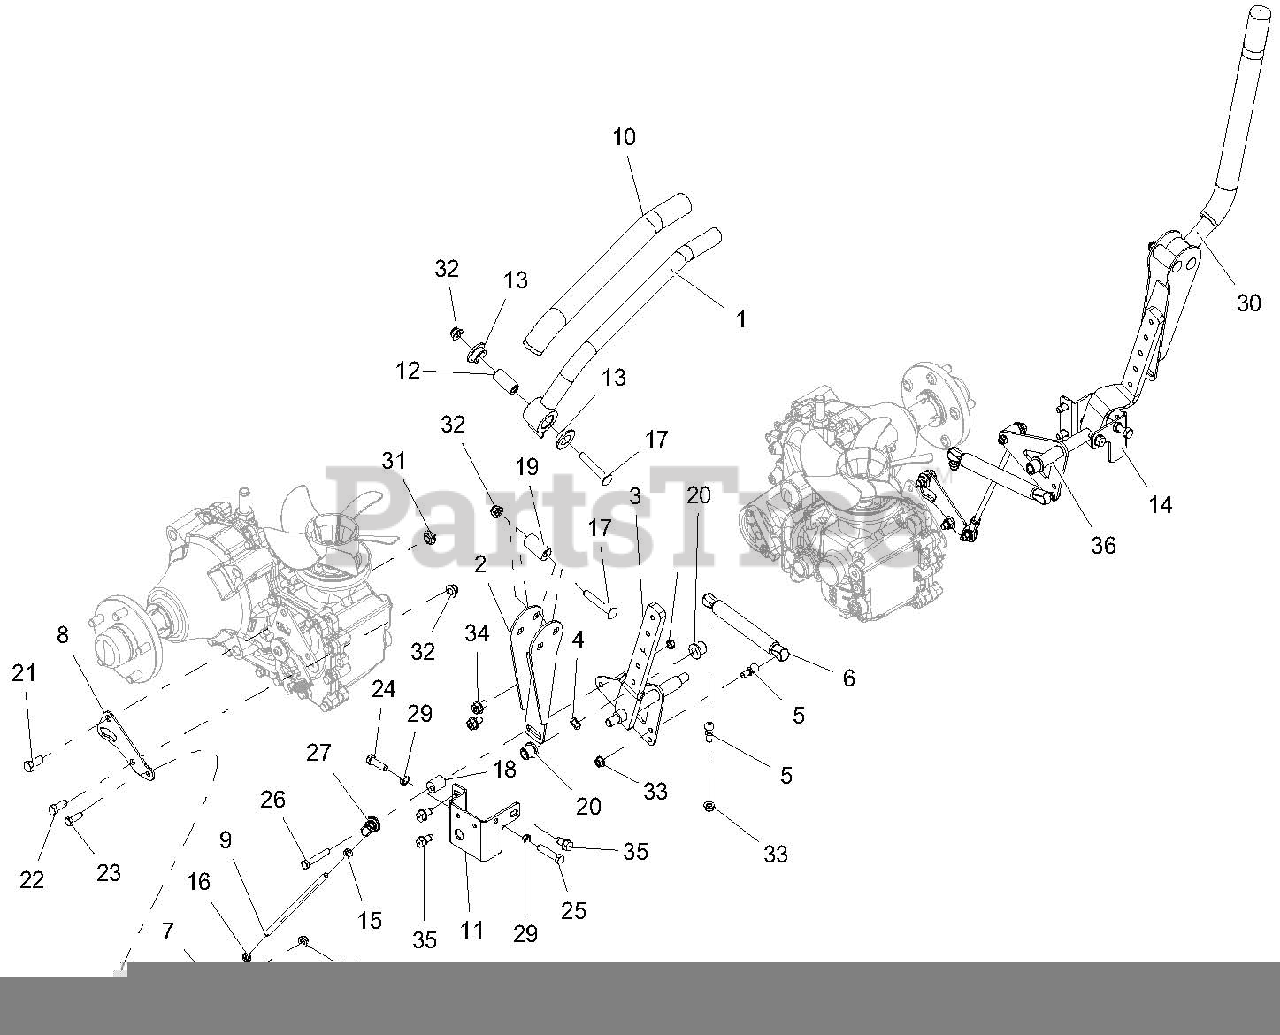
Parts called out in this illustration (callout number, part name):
1	WLDMT, RH CONTROL HANDLE
2	WLDMT, UPPER ADJUSTABLE CONTROL ARM
3	WLDMT, RH LOWER CONTROL ARM
4	WAVE WASHER .531X.781X.125 FH
5	STUD-BALL
6	DAMPER,
7	ALIGNABALL, 5/16 LH THREAD
8	BRKT., CONTROL MTG-BLACK
9	ROD, STEERING
10	GRIP, HANDLEBAR
11	BRKT, RH CONTROL ARM STOP
12	SPCR, STEERING ARM
13	BSHG, FLANGE .762 X 1.48 X .44 NYLON
14	BRKT, LH CONTROL ARM STOP
15	NUT-JAM
16	NUT, JAM -LH .31-24 YWZC
17	BLT-RHDSSQNK .38-16X2.50 G5YZ
18	ECCENTRIC
19	BSHG, ECCENTRIC .328 X .750 X 1.625
20	BHSG-FLG .500X.750X.750X.125
21	BLT-HEX .44-14X1.00 GR5 YWZC
22	BLT-HEX .38-16X1.00 GR5 YWZC
23	BLT-HEX .31-18X1.00 GR5 YWZC
24	BLT-HEX .38-16X1.25 GR5 YWZC
25	BLT-HEX .38-16X1.75 GR5 YWZC
26	BLT-HEX .31-18X2.00 GR5 YWZC
27	ALIGNABALL, 5/16 RH THREAD
28	NUT-LK-CTR .31-18 YWZC
29	NUT, JAM .375-16 YWZC
30	WLDMT, LH CONTROL HANDLE
31	NUT-LK-NYL-FLG .44-14 YWZC
32	NUT-LK-NYL-FLG .38-16 YWZC
33	NUT, LK-TOP-FLG .312-18 YWZC
34	BLT-SERHFWH .38-16X.62 YWZC
35	SCR-TAP .38-16X.75 HWH TR YWZ
36	WLDMT, LH LOWER CONTROL ARM
